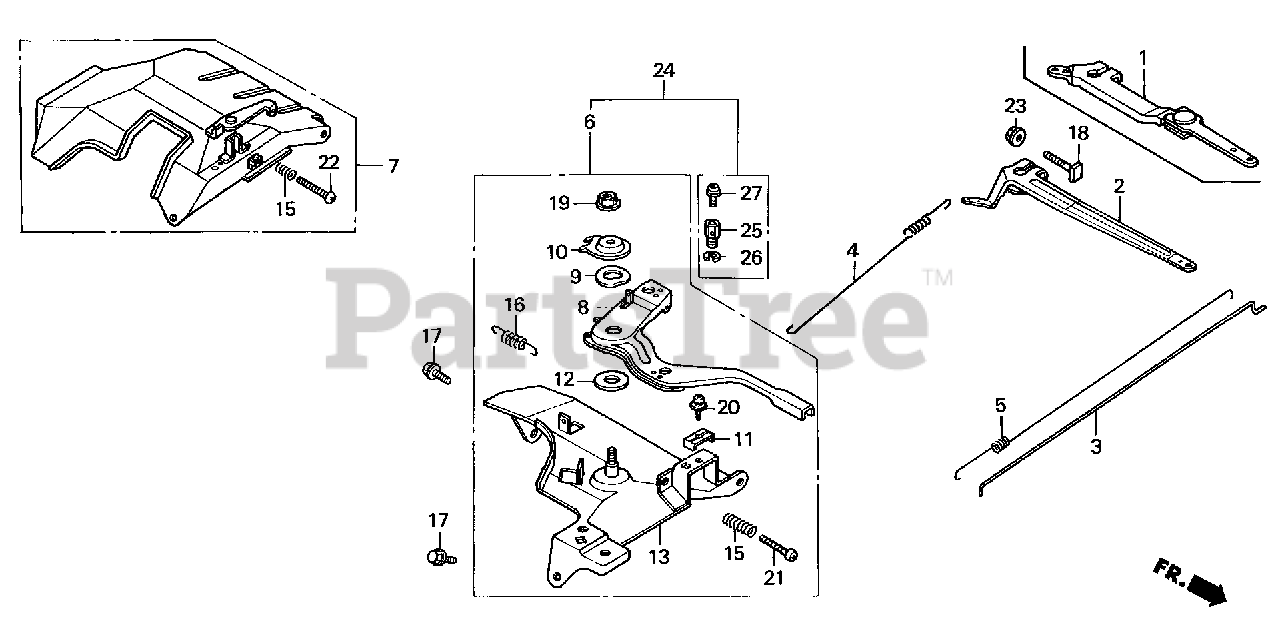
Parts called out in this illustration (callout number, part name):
2	ARM, GOVERNOR
3	ROD, GOVERNOR
4	SPRING, GOVERNOR
5	SPRING, THROTTLE RETURN
8	LEVER, CONTROL
9	SPRING, LEVER
10	WASHER, CONTROL LEVER
11	HOLDER, CABLE
12	SPACER, CONTROL LEVER
13	BASE, CONTROL
15	SPRING, CONTROL ADJUSTING
16	SPRING, CABLE RETURN
17	BOLT, FLANGE (6X12) (CT200)
18	BOLT, GOVERNOR ARM
19	NUT, SELF-LOCK (6MM)
20	SCREW, PAN (5X16)
21	SCREW, PAN (5X32)
23	NUT, FLANGE (6MM)
24	CONTROL ASSY. (REMOTE)
25	HOLDER, WIRE
26	CIRCLIP (5MM)
27	SCREW, PAN (4X6)
